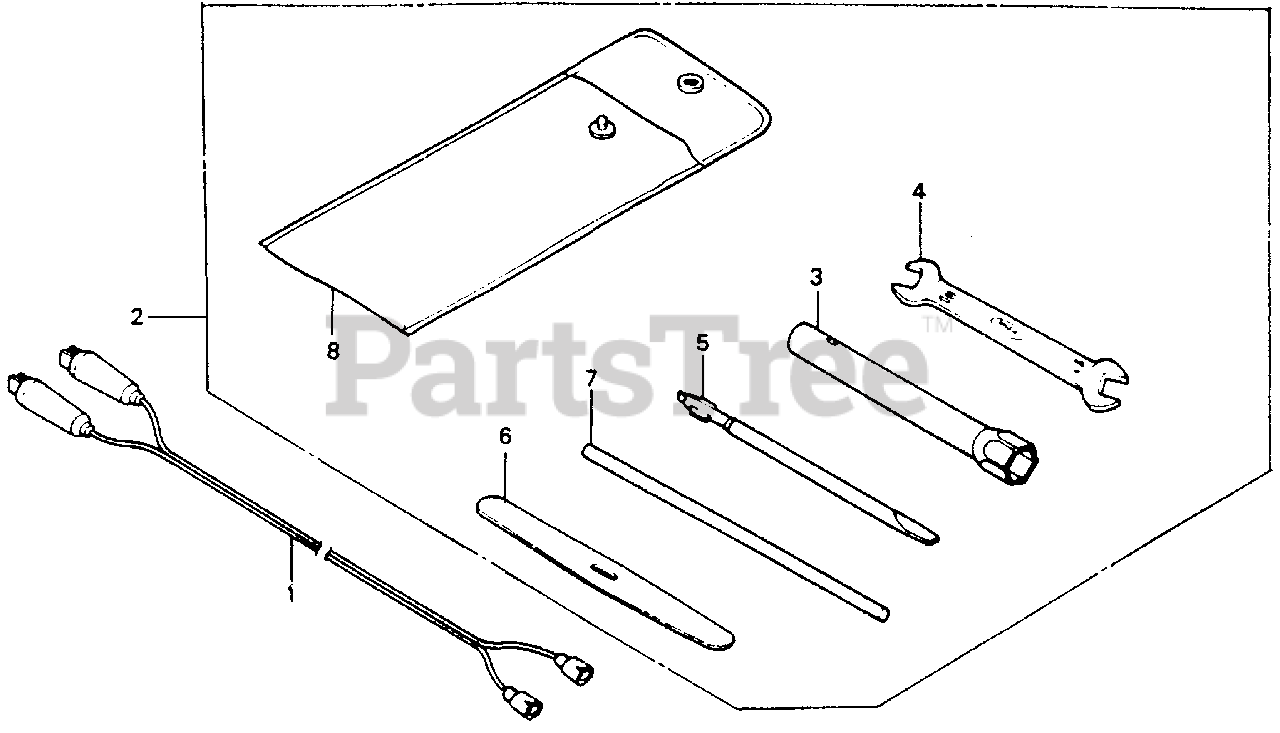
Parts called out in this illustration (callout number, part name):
1	WIRE ASSY., CHARGE
3	WRENCH, PLUG
4	WRENCH (10X12) (OPEN END)
5	SCREWDRIVER 3, STRAIGHT SLOT (NO.2)
6	LEVER, TIRE
7	BAR A, HANDLE
